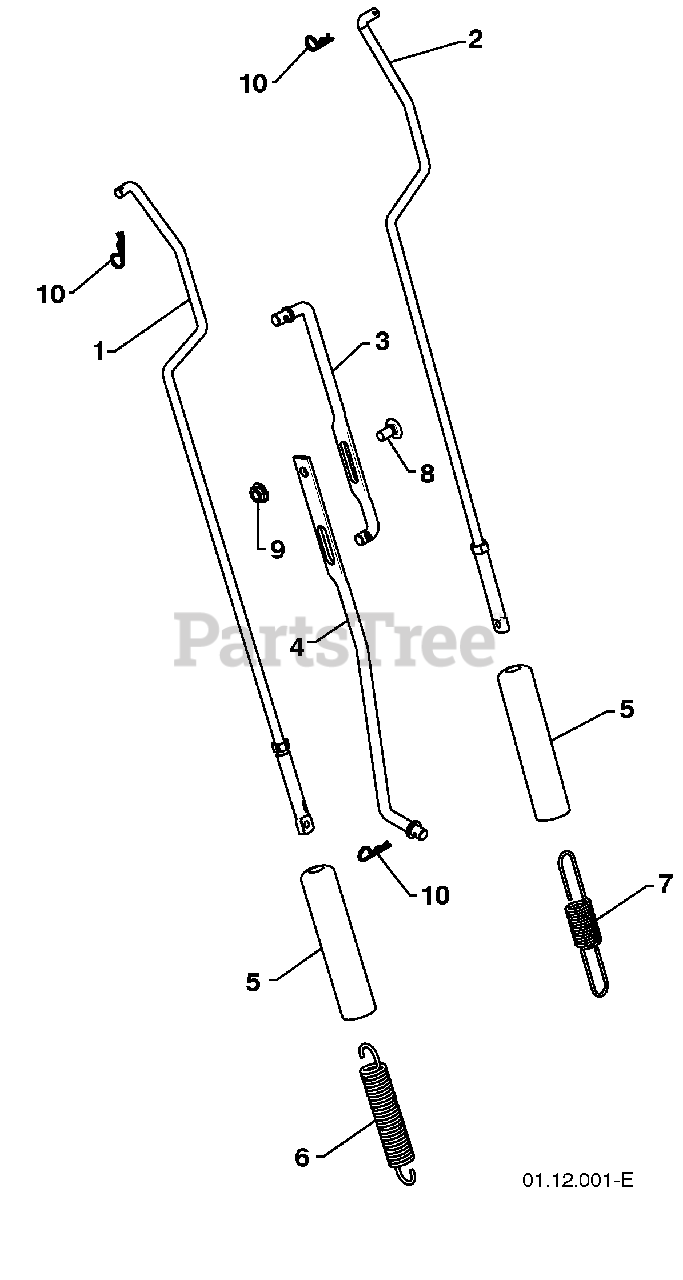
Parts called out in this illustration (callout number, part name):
1	IMPELLER ROD ASSEMBLY
2	TRACTION ROD ASSEMBLY
3	SHIFTER ROD TOP
4	SHIFTER ROD BOTTOM
5	SPRING SLEEVE
6	IMPELLER SPRING
7	TRACTION SPRING
8	CARRIAGE BOLT 5/16-18 X .75
9	NUT 5/16-18
